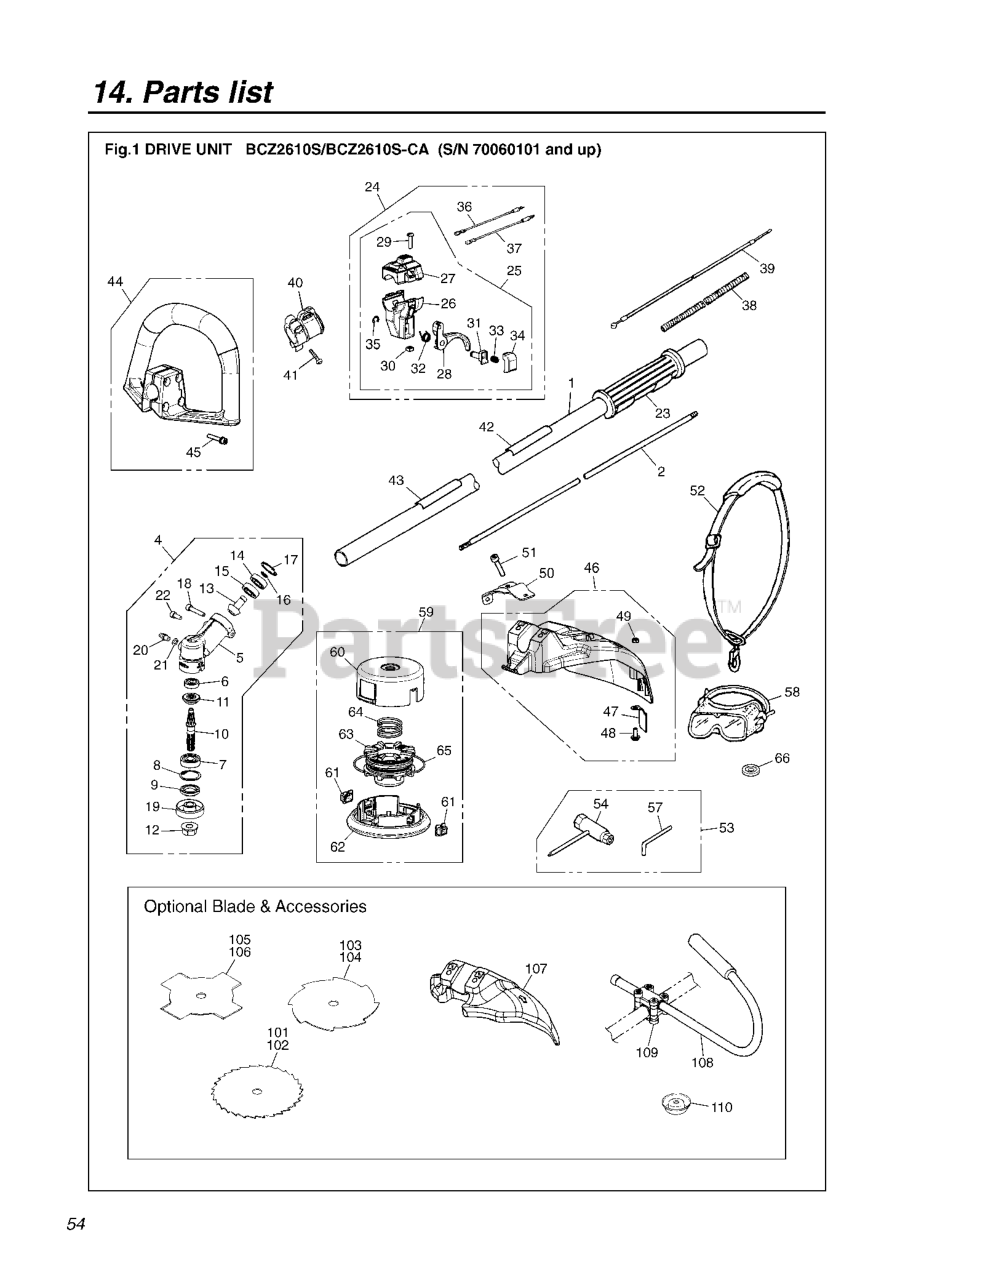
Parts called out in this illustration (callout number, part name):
1	PIPE COMP
4	RP_GEARCASE ASSY.
5	GEARCASE
8	RING,SNAP M26x1.2 RP-318013340
15	BALL BEARING
18	BOLT TORX
19	HOLDER(A)
22	BOLT, TORX
24	LEVER COMP (RPLS 8488R20343)
25	LEVER (FLEX. LEVER)(RPLS -13)
27	COVER COMP (RPLS 611014410-02)
28	THROTTLE TRIGGER
36	CORD (A), BLACK
37	CORD (B), RED
40	HANGER COMP.
42	LABEL NAME FOR BCZ2610S
43	LABEL CAUTON FOR BC
44	HANDLE ASSY. (RPLS T319514001)
46	GUARD COMP
47	BLADE (RPLS T300224120)
51	BOLT, TORX
52	STRAP ASSY
53	TOOL SET (RPLS 848-8UD-0120)
54	SOCKET
58	GOGGLExxx (RPLS
59	4" TAP TRIMMER HEAD PT104
60	TAP HEAD RPLS T318915100/02
61	EYELET
62	COVER (RPLS T318915131)
63	HOLDER, CORD (RPLS T318915141)
66	HOLDER (B)
101	Brushcutter Blade, 22 Tooth 9"
102	Brushcutter Blade, 24 Tooth 9"
103	BLADE, 8
104	Brushcutter Blade, 8 Tooth 9"
105	BLADE, 8
106	Brushcutter Blade, 4 Tooth 9"
108	HANDLE(L)
109	BRACKET A
110	COVER (10MM)
